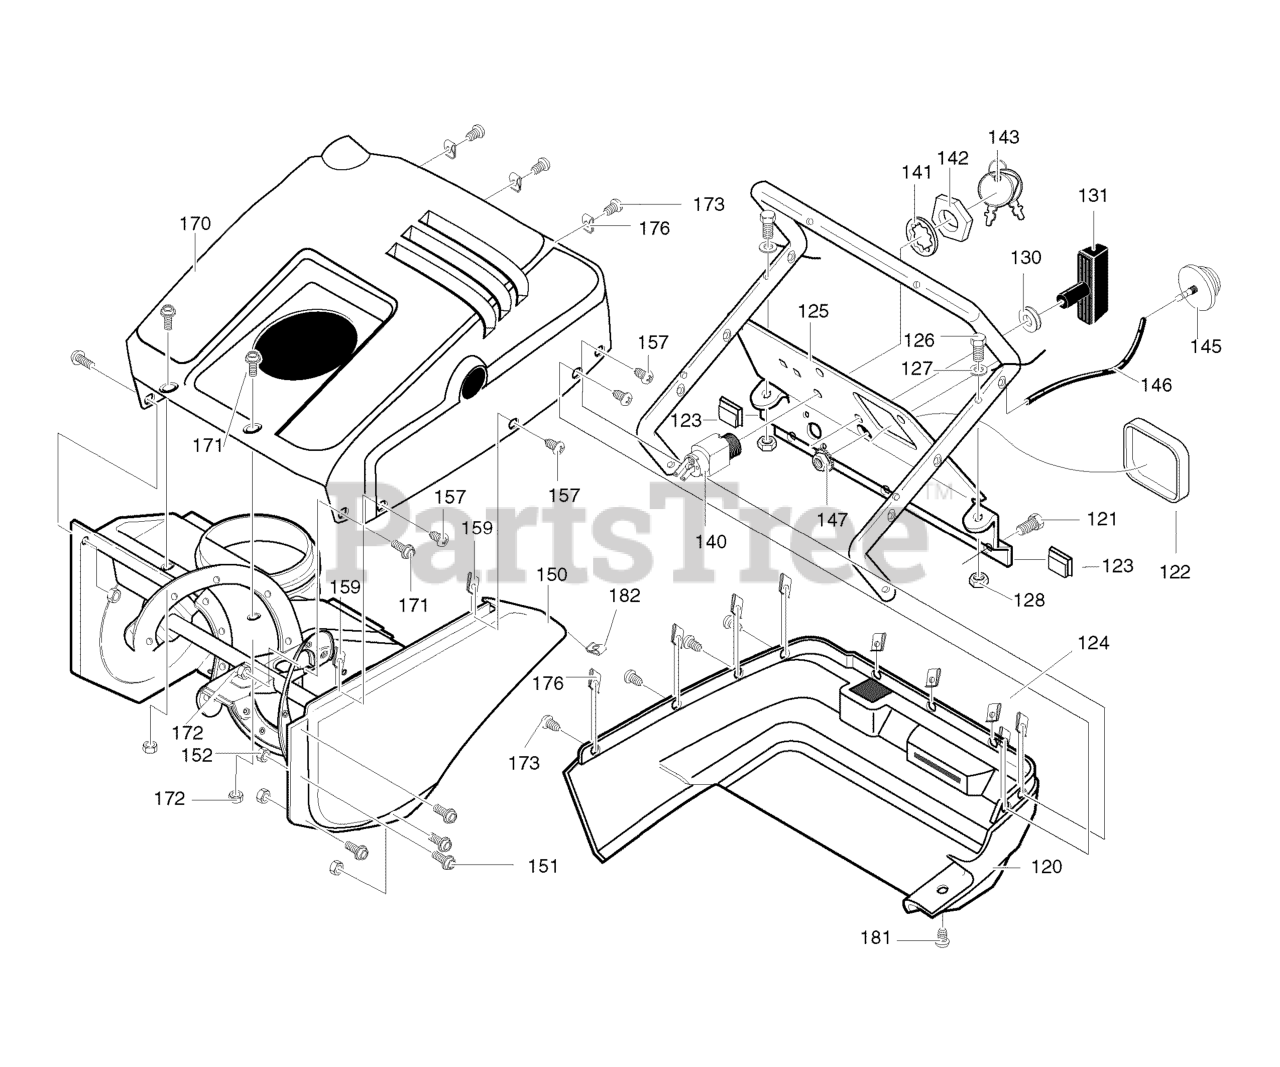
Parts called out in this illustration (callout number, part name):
120	COVER, BOTTOM
121	SCREW, 1/4-14 X .75
122	PANEL, SPARK ACCESS
123	CLIP, "S" TINNERMAN
124	NUT, 1/4-10 SPEED J TYPE
125	CONTROL PANEL
126	SCREW, 1/4-20 X 1.25
127	FLATWASHER, .281 X .63 X .065
128	NUT, 1/4-20 HEX HEAD CENTER LOCK
130	GOMMET & WASHER
140	SWITCH, IGNITION
141	WASHER, INTERAL TOOTH LOCK .640 x 1.1 x .05
142	NUT. 5/8-32
143	KEYS & RING
145	PRIMERBULB
146	HOSE PRIM 9.50LG
147	NUT, 1/4-20 HEX HEAD KEPS
150	COVER, BELT
151	SCREW, 10-24 X .50
152	NUT, #10-24 HEX HEAD CENTER LOCK
157	SCREW, 1/4-14 X .75
159	NUT, 1/4-10 SPEED J TYPE
170	COVER, TOP
171	SCREW,#10-24 X .50
172	NUT #10-24 HEX HEAD CENTER LOCK
173	SCREW, 1/4-14 X .75
176	NUT, 1/4-10 SPEED J TYPE
181	SCREW, 1/4-14 X .75
182	NUT 1/4-10 SPEED J TYPE
